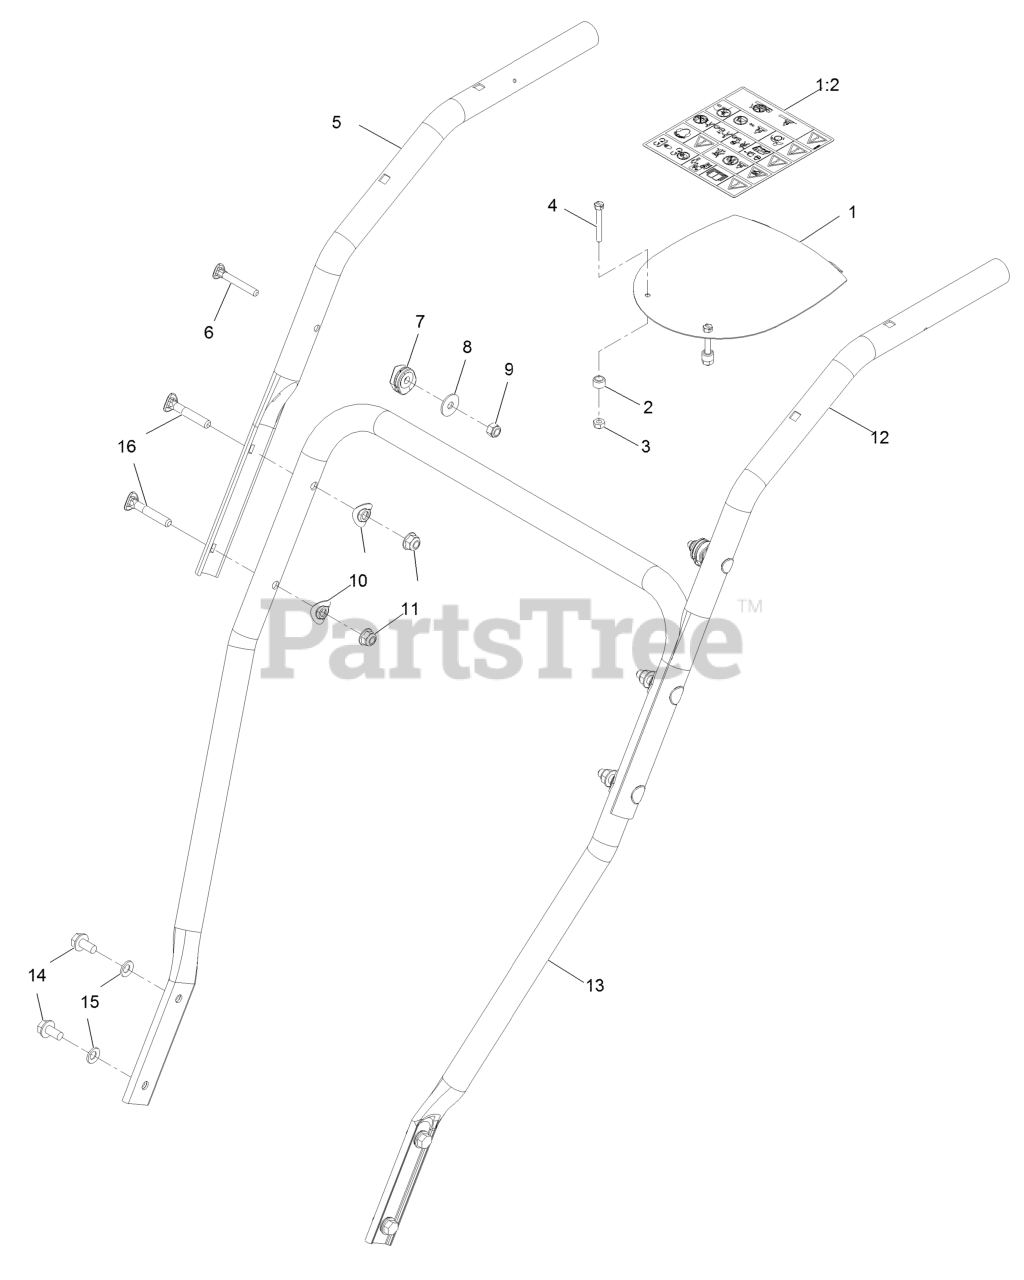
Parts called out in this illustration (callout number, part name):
1	Panel-Control
1:2	Decal-Console
2	Spacer-Blade, Rotor
3	Nut-Nyloc #10-24
5	Handle-Upper, RH
7	Clamp-Cable
8	Washer-Plain
9	Nut-Nyloc 1/4-20
11	Nut-Nyloc 5/16-18 Flg
12	Handle-Upper, LH
13	Handle-Lower
14	Screw-HWHTF
15	Washer-Belleville
16	Screw-Handle
